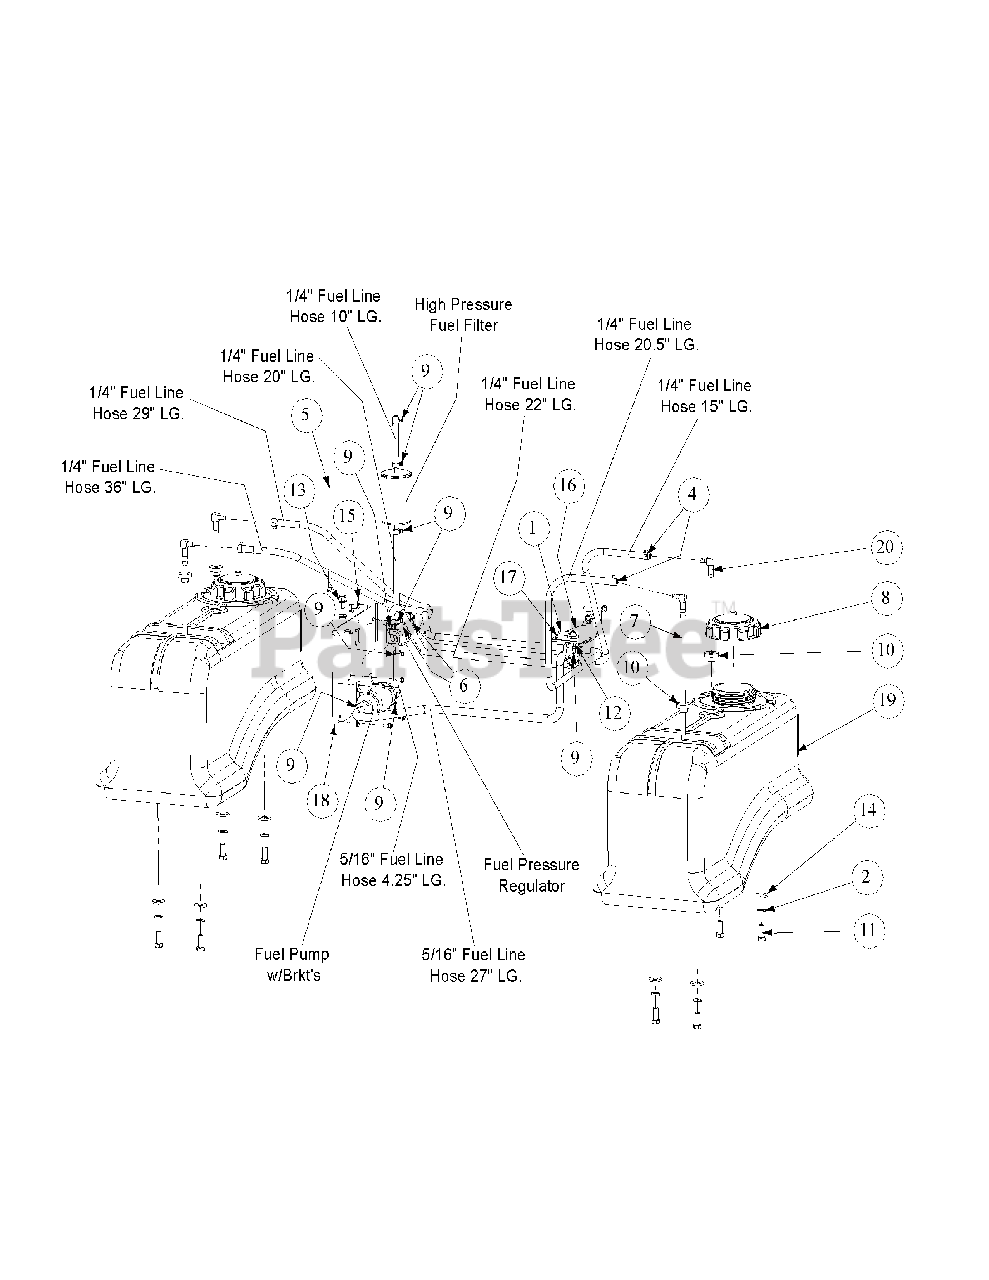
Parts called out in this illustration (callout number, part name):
1	Fuel Shut Off Valve
2	Lock Washer, 3/8
3	Hose, 1/4" Fuel Line (in inches)
4	Clamp, Union
5	Cable Tie
6	HHCS, 1/4-20, .750
7	Fuel Fitting
8	Fuel Cap, 3.5
9	Hose Clamp
10	Fuel Tank Grommet
11	Hex, Cap Screw, 3/8-16, .88
12	Lock Washer
13	Flat Washer, 5/16
14	Flat Washer, .406 ID, 1.0 OD, .105
15	Lock Nut, 1/4-20
16	Fuel Valve Mounting bracket
17	Label, Fuel Tank Shut Off
18	Pump Control Mounting Bracket
19	Fuel Tank
20	Fuel Return Fitting
21	Hose, 5/16" Fuel Line 31.25"
